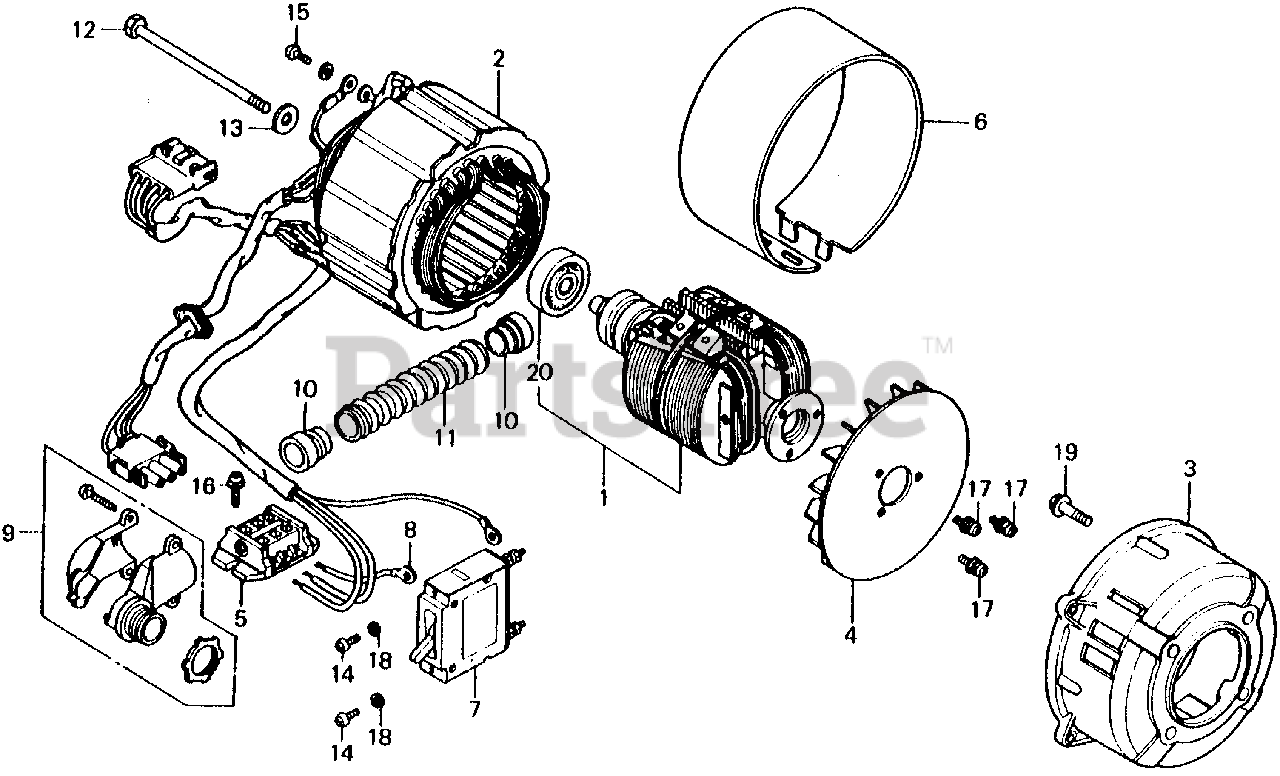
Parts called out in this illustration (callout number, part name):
1	ROTOR
2	STATOR (NOT AVAILABLE)
3	HOUSING, FR.
5	TERMINAL (3P) (NOT AVAILABLE)
6	COVER, STATOR *NH31* (MCKINLEY WHITE)
7	BREAKER, CIRCUIT (35A) (NOT AVAILABLE)
8	WIRE, CIRCUIT BREAKER
9	FITTING (NOT AVAILABLE)
11	CONDUIT, FLEXIBLE METAL
12	BOLT, HEX. (5/16X188)
13	WASHER (8MM)
14	SCREW, PAN (3X8)
15	SCREW, PAN (5X12)
16	SCREW-WASHER (5X12)
17	SCREW, TAPPING (5X14)
17	SCREW-WASHER (5X14)
18	WASHER, SPRING (3MM)
19	BOLT, FLANGE (8X28)
20	BEARING, RADIAL BALL (6304UU)
